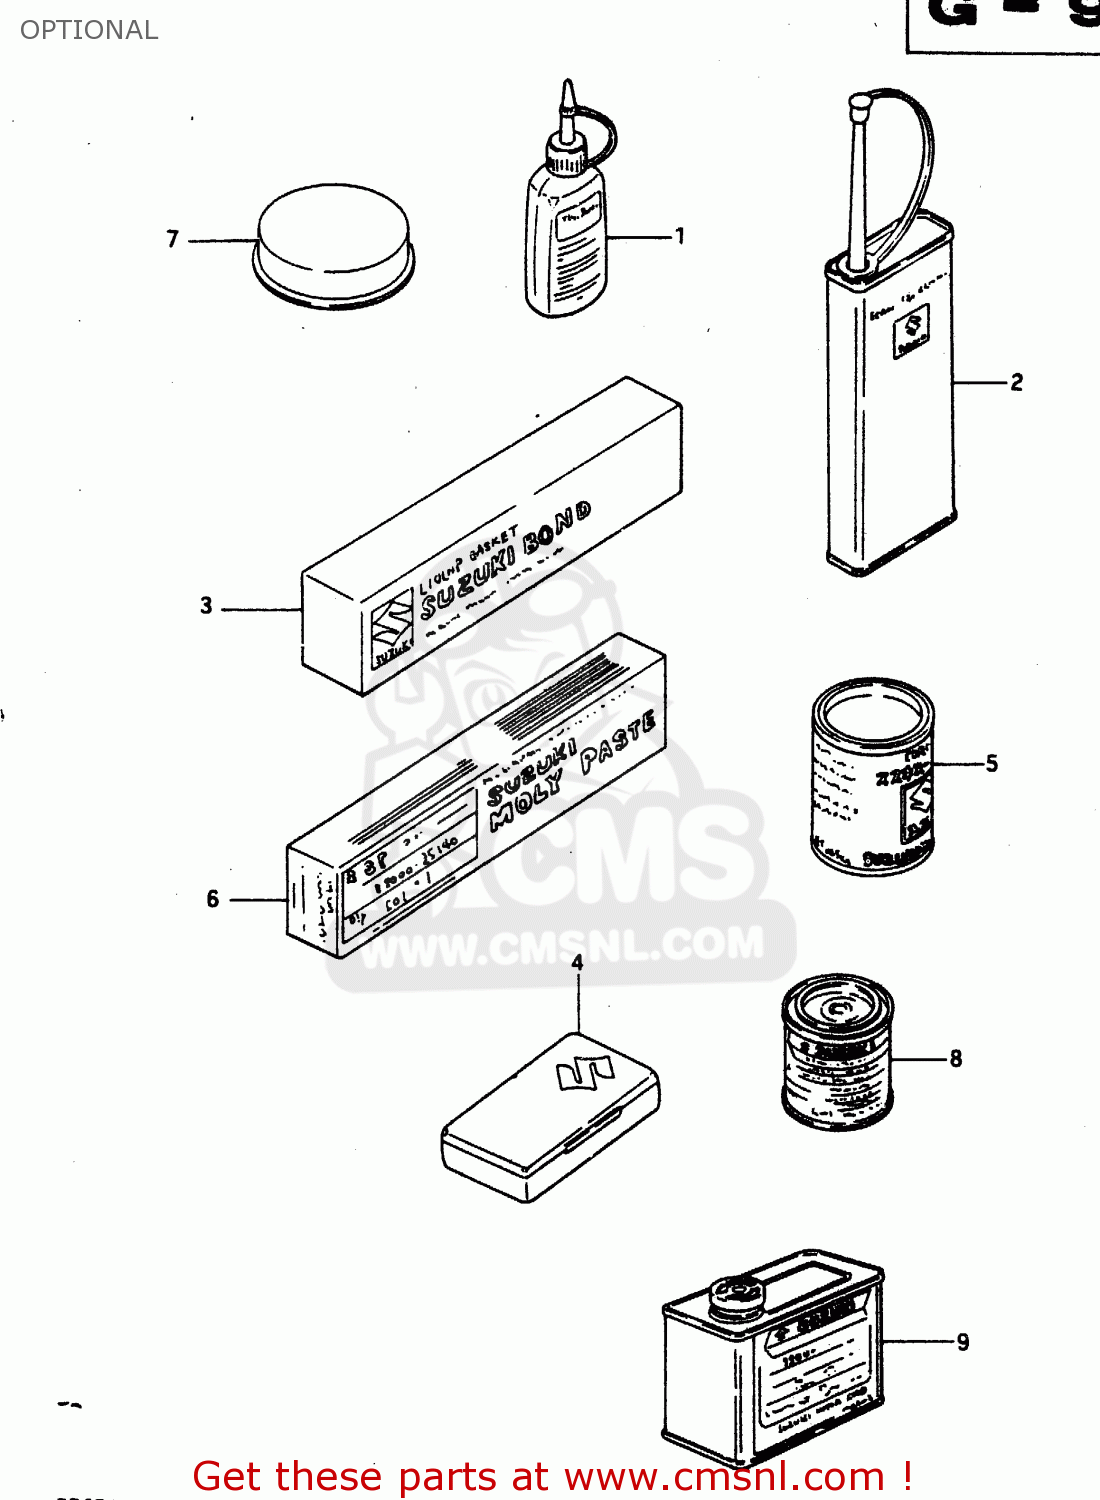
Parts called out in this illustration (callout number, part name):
1	THREAD LOCK NO.1342
2	THREAD LOCK NO.1401 CLEAR 200G
3	LIQUID GSKT NO.1207B 100G BLK
4	TUBE REPARING TOOL
5	GREASE(C)EP2 LITHIUM 150G
6	SUZUKI MOLY PASTE
7	GREASE,PBC FOR BRK PAD 20G
8	PAINT,BLACK
9	PAINT (PARSEC BLUE)
